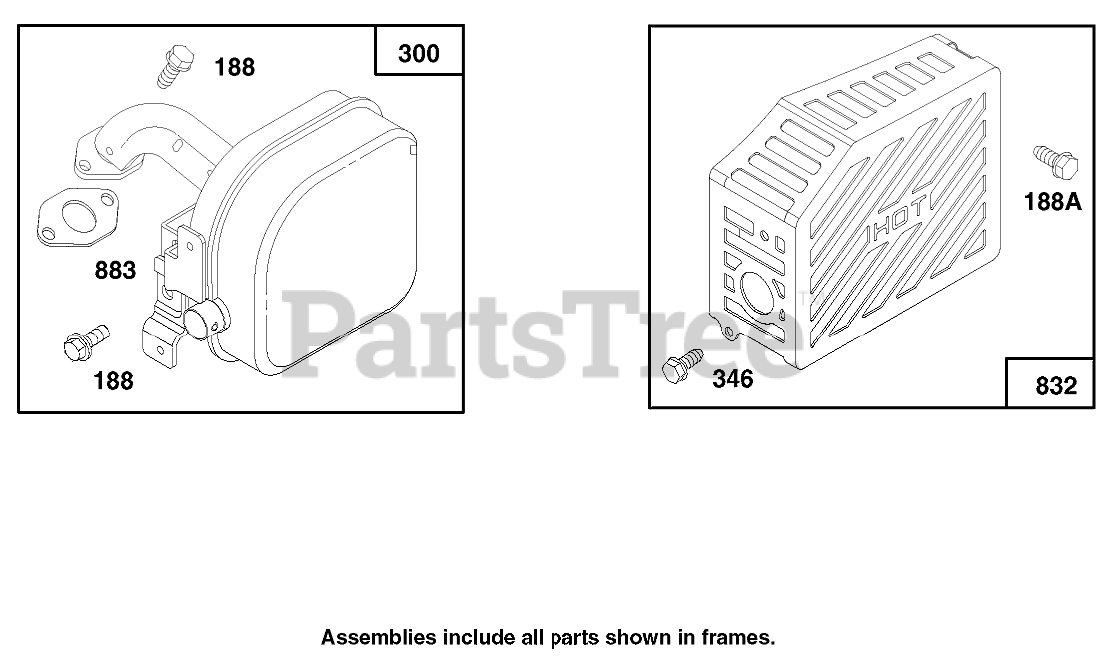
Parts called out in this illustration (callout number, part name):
188	Screw-Cap
188A	SCREW - HEX HEAD
300	MUFFLER - EXHAUST
346	Screw-Hex
832	Guard-Muffler
883	EXHAUST GASKET
